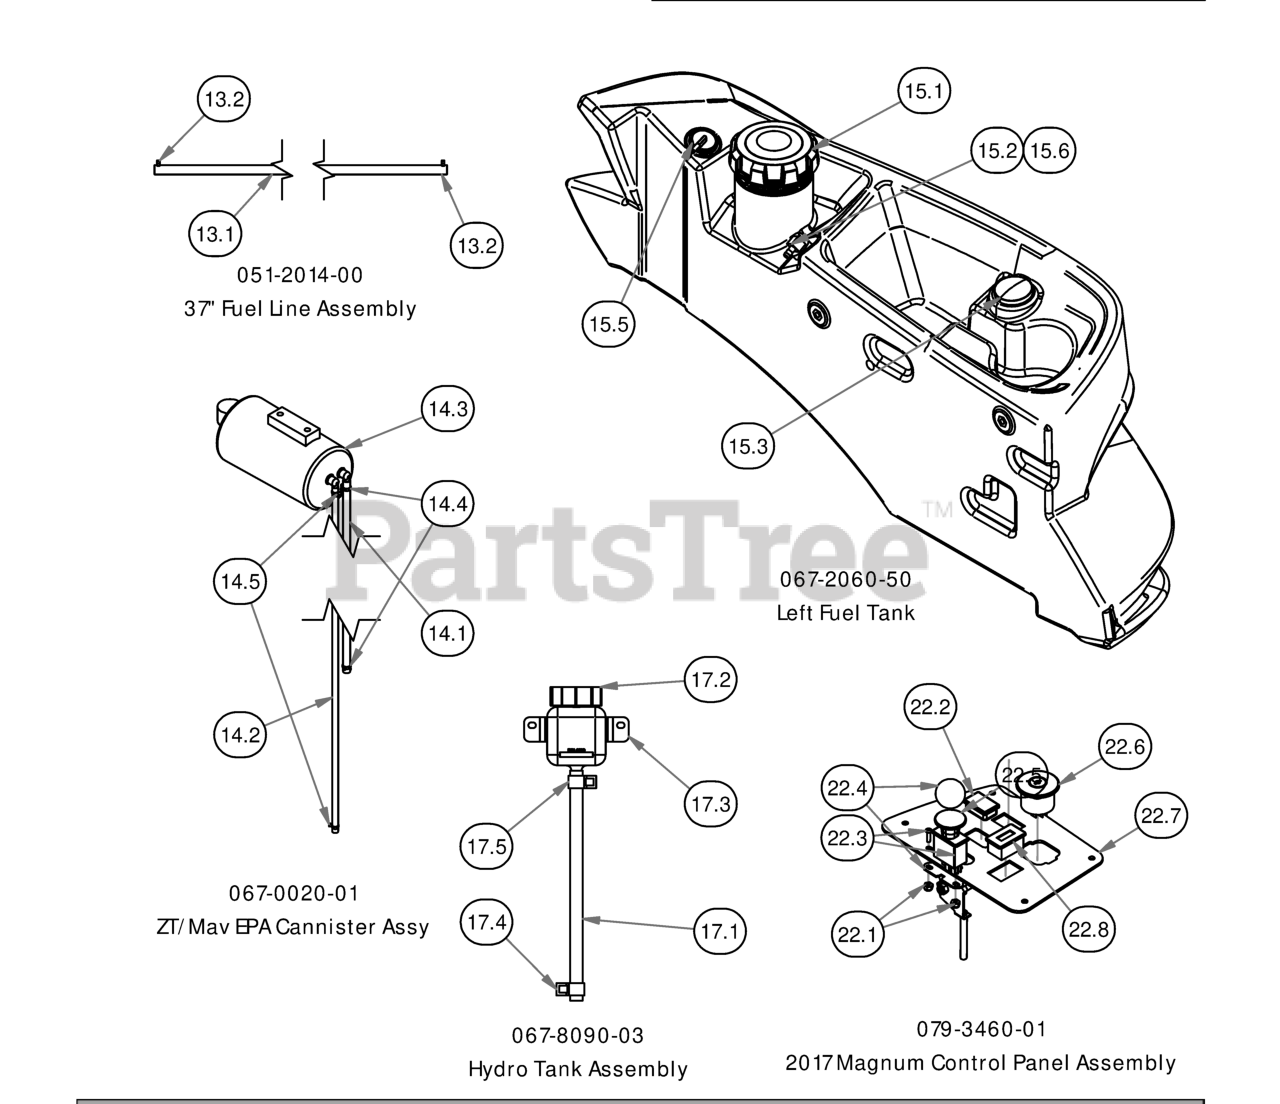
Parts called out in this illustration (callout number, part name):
13.1	37" 1/4 Fuel Line
13.2	1/4 Fuel Hose Clamp
14.1	1/4" Vinyl Tubing, 46" Long
14.2	3/16" Vinyl Tubing, 55" Long
14.3	Carbon Canister
14.4	3/16 Vinyl Clamp
14.5	3/16" Vinyl Hose Clamp
15.3	Fuel Gauge w/Grommet
15.5	Rollover Valve W/Grommet
15.6	Pick-Up Grommet
17.1	ZT/Maverick Hydro Tank Hose
17.2	Hydraulic Tank Cap
17.3	350ml Expansion Tank
17.4	3/8" Hose Clamp
17.5	1/2 Hose Clamp
22.1	10-24 Nylon Insert Locknut Zinc Orange Nylon
22.2	Light Plug
22.3	10-24 X 5/8 BS Button Head Bolt
22.4	Throttle Lever Assembly
22.5	PTO Engager
22.6	Ignition Switch
22.7	Control Panel
22.8	Tachometer
